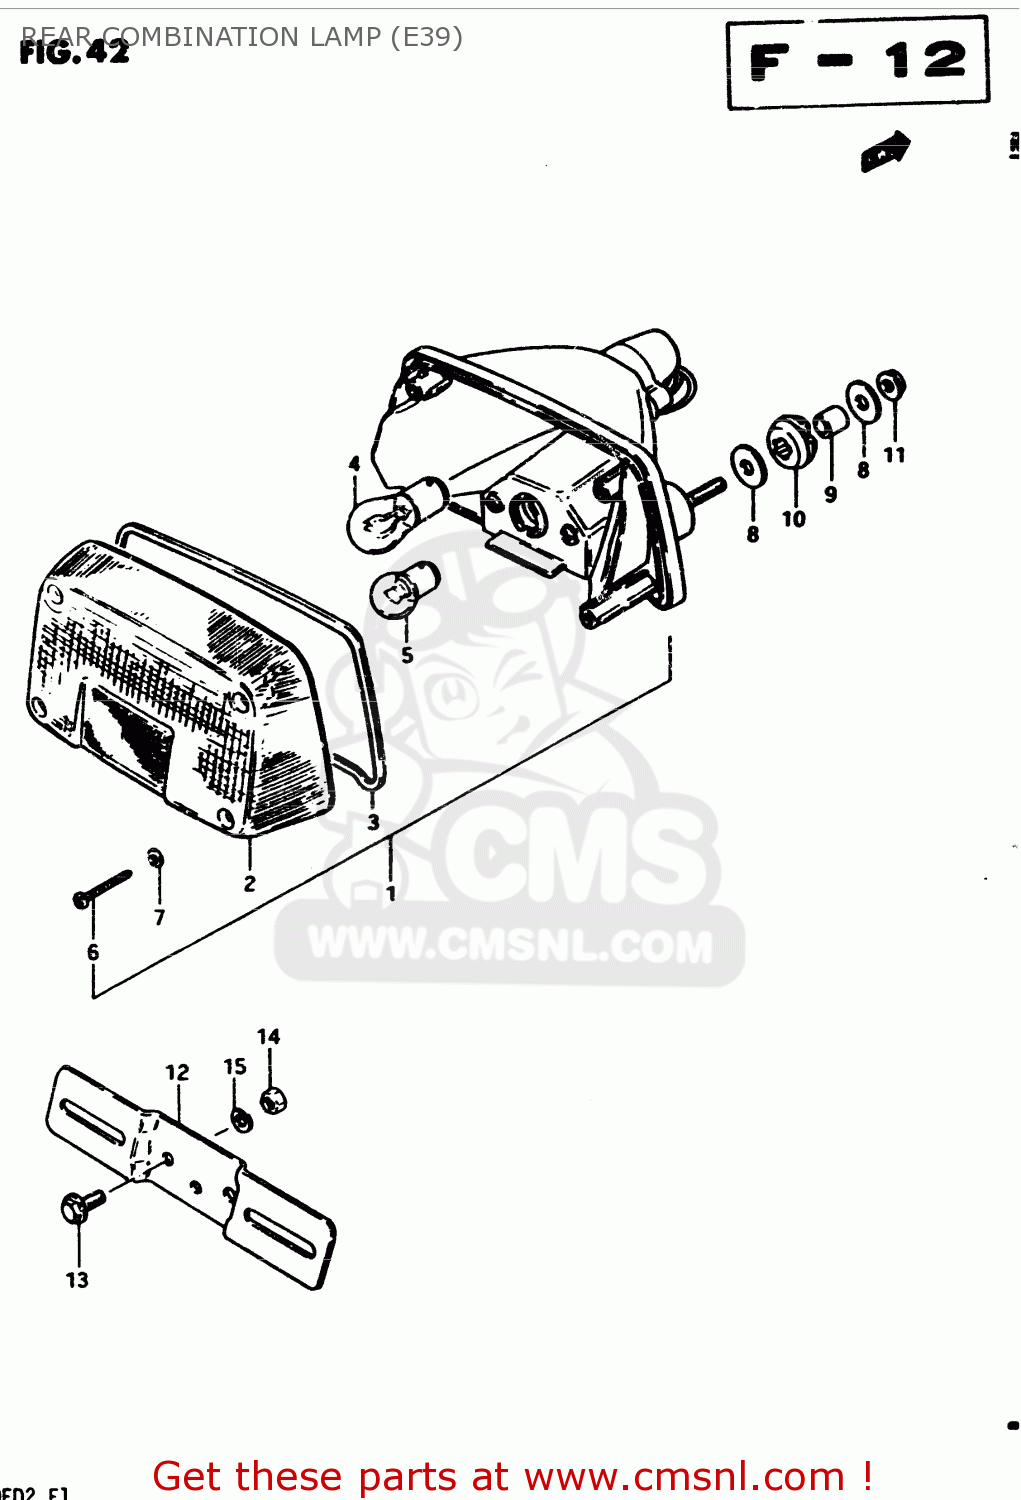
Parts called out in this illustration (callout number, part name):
1	LAMP ASSY, REAR COMBINATION
2	LENS,RR COMBI
3	GASKET
4	BULB(12V21/5W)
5	BULB
6	SCREW
7	GASKET (NAS)
8	WASHER
9	SPACER (6.8X10X11.5)
10	CUSHION
11	NUT 6MM
12	BRACKET, LICENSE PLATE
13	BOLT
14	NUT
15	LOCK WASHER
